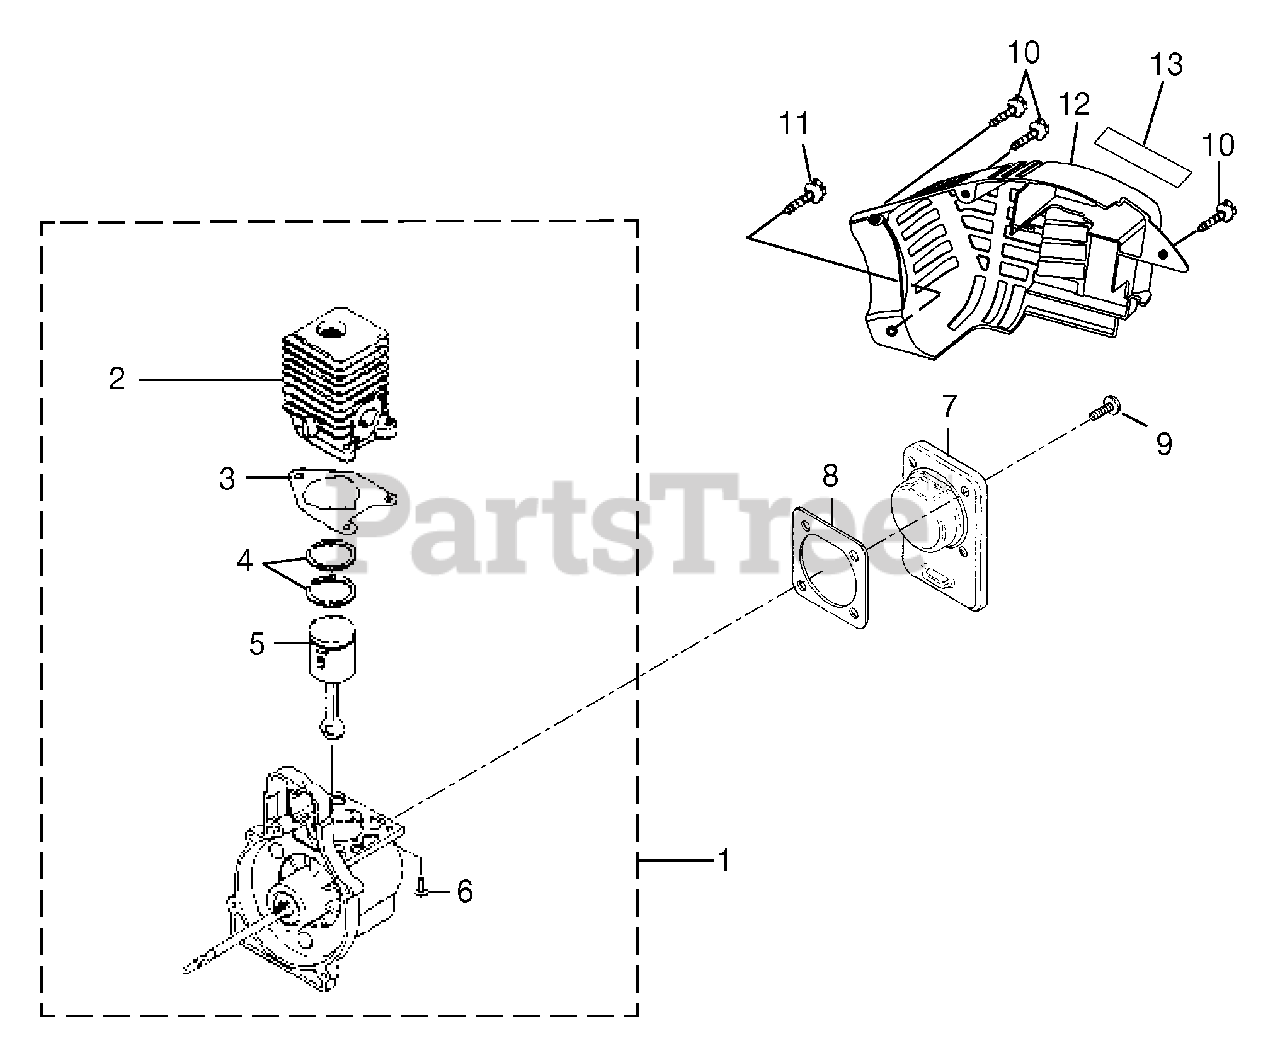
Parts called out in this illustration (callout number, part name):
1	SHORT BLOCK (30cc)
2	30cc CYLINDER
3	CYLINDER GASKET
4	PISTON RING (30CC)
5	30cc PISTON AND ROD
6	SCREW (12-24 x 660 in TORX PAN HD)
7	CRANKCASE COVER
8	CRANKCASE GASKET
9	SCREW (10-24 x 9/16 in PAN HD)
10	SCREW (#8 x 1/2 in PAN HD)
11	SCREW (#10 x 3/4 in TORX TRUSS HD)
13	ZIP START DECAL
